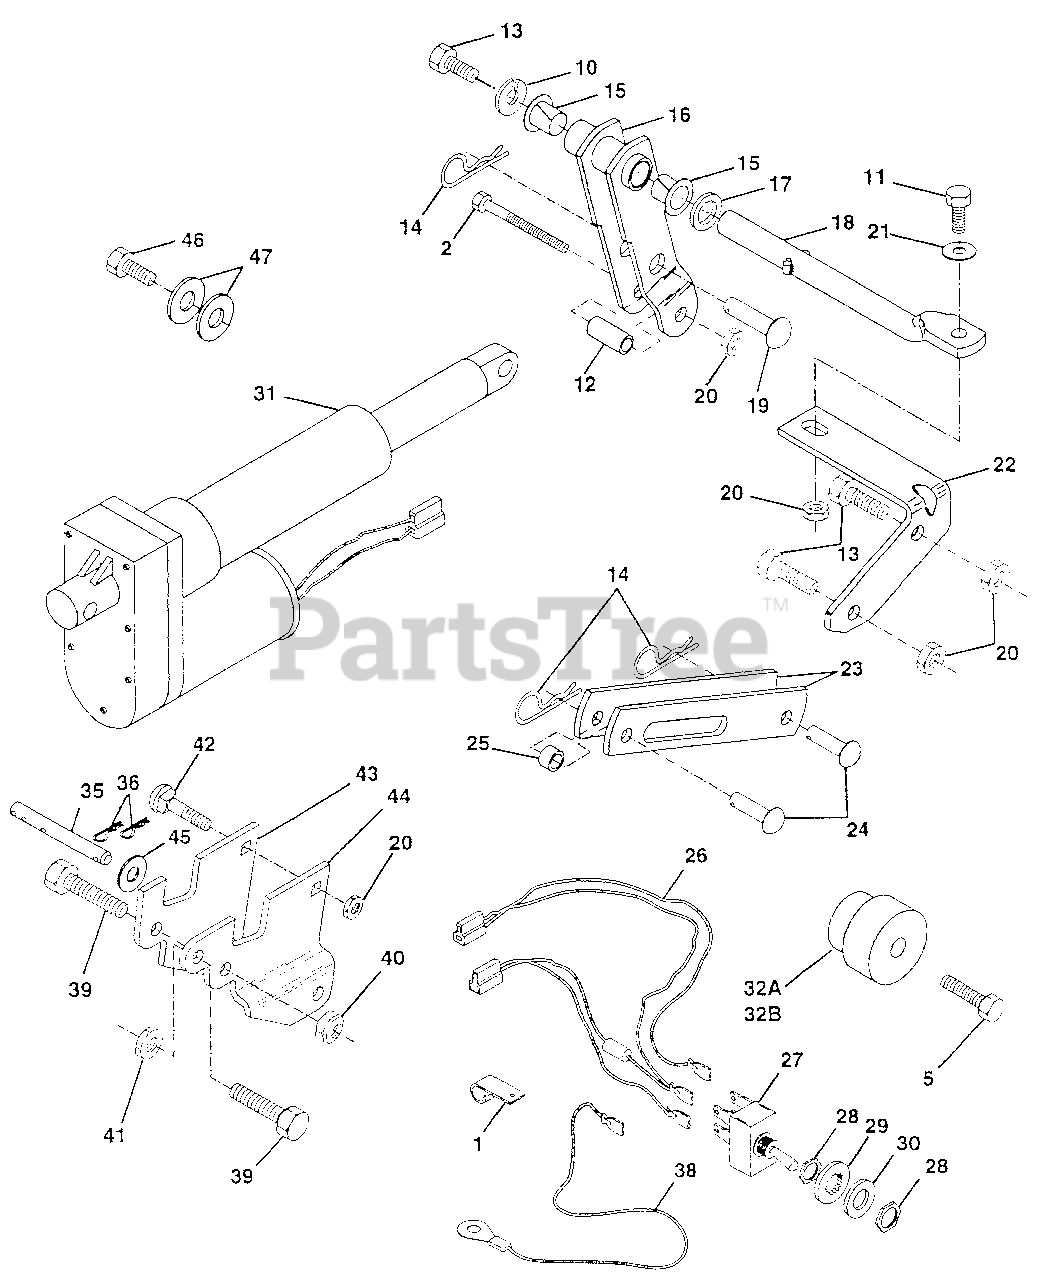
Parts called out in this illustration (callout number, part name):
1	Clip, Insulated
2	Bolt, Hex 3/8-16 x 2-1/4 Grade 5
5	Bolt, Hex 3/8-16 x 1-3/8
10	Washer, Lock
11	Bolt, Hex 3/8-16 x 1-1 /4
12	Bushing .384 x 1/2 x 1-1/4
13	Bolt, Hex 3/8-16 x 7/8
14	Spring, Retainer
16	Arm, Pivot
17	Washer 21/32 x 1 x 21 Ga.
18	Rod, Pivot Support
19	Pin, Pivot
20	Locknut 3/8-16
21	Washer 13/32 x 7/8 x 16 Ga.
22	Bracket, Pivot Rod
23	Link, Lift
24	Pin, Pivot
25	Spacer
26	Harness, Lift Kit
27	Switch, Lift
28	Nut, Switch
29	Washer, Lock Int. Tooth
30	Washer 15/32 x 3/4 x 16 Ga.
31	Electric, Actuator
32A	Hub, Lever Lift (Splined)
32B	Hub, Lever Lift (Tapered)
35	Pin, Actuator
36	Spring, Retainer
38	Wire, Ground
39	Bolt, Hex 7/16-14 x 1-1/4
40	Jam Nut 7/16-14
41	Locknut 7/16-14
42	Carraige Bolt 3/8-16 x 1-1/4
43	LH Actuator Bracket, Hydro
44	RH Actuator Bracket, Hydro
45	Washer 17/32 x 3/4 x 16 Ga.
46	Bolt, Hex 5/16-18 x 1-1/4
47	Washer 11/32 x 1-1/2 x 10 Ga.
